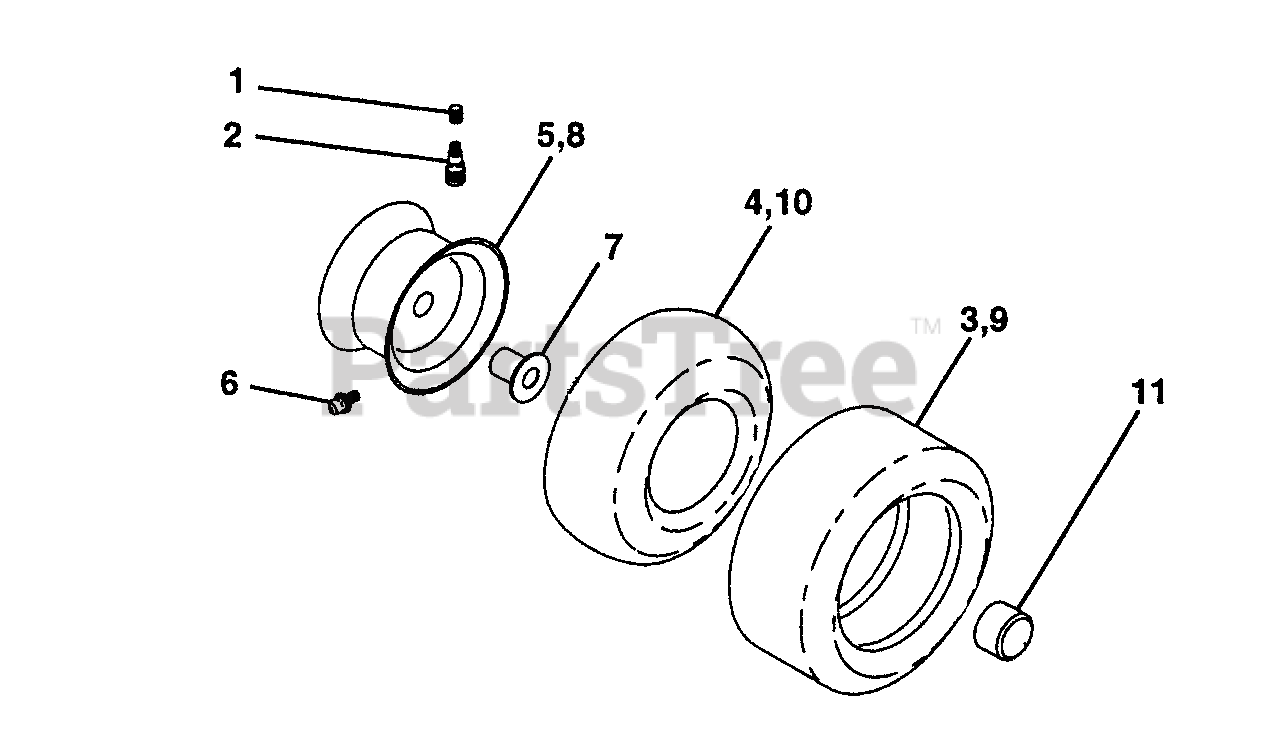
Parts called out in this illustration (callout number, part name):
1	Cap Valve Tire
2	Stem Valve
3	Tire F Ts 15 X 6 0 - 6 Service
4	Tube Front
5	Rim Asm 6"front Silver Service
6	Fitting Grease
7	Bearing Flange
8	Rim Asm 8"rear Silver Service
9	Tire R Ts 20 x 10-8 C Service
10	Tube Rear
11	Cap Axle Blk 1 50 X 1 00
